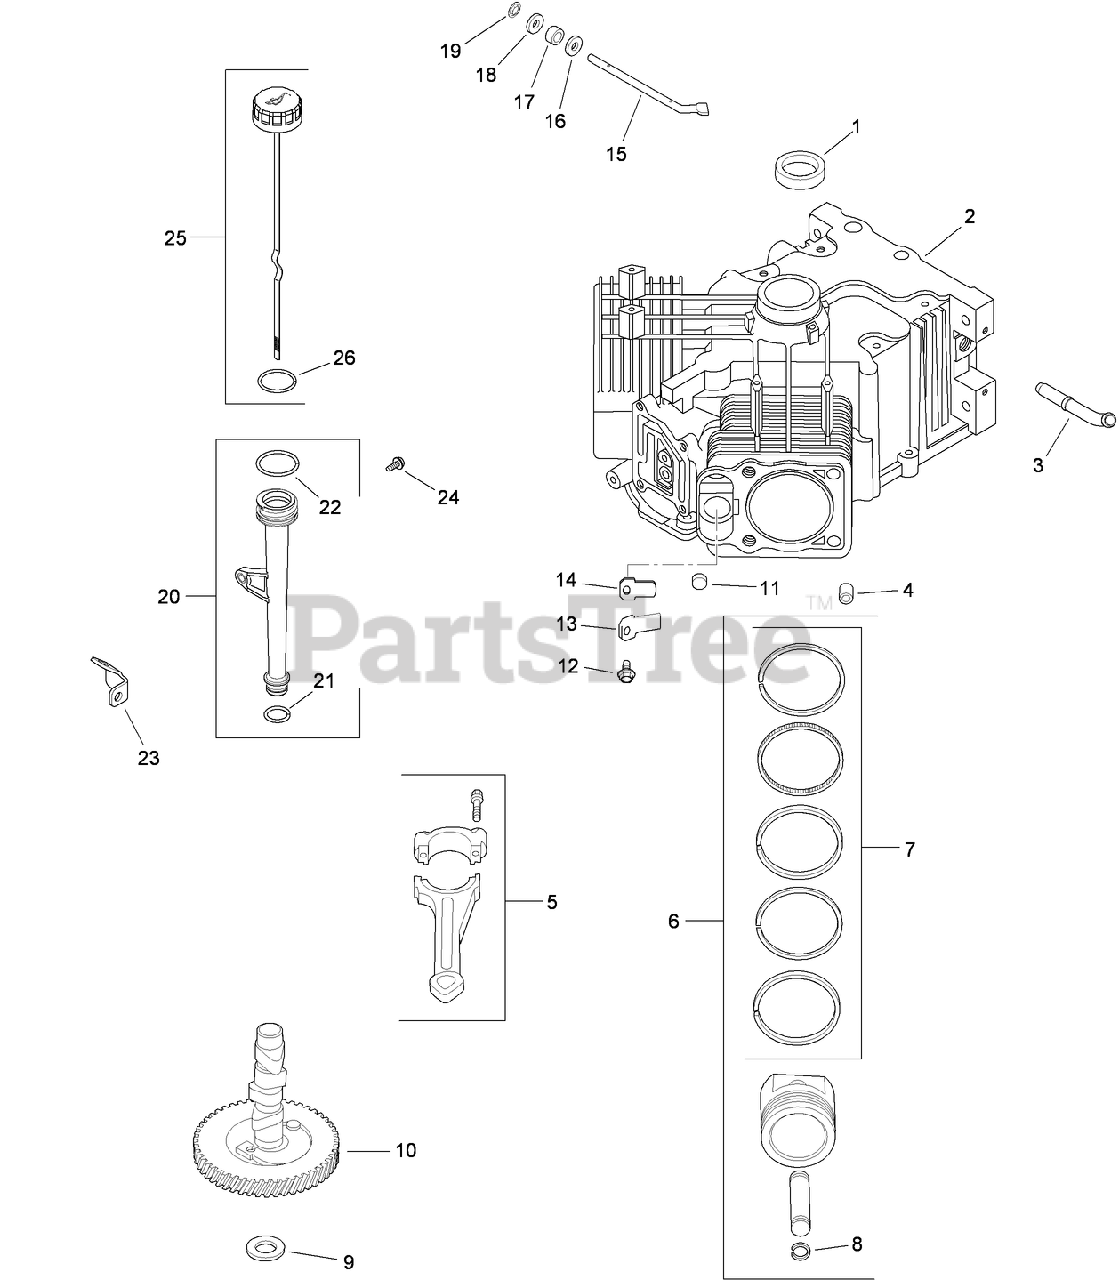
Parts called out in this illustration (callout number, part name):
1	SEAL-OIL
2	SHORT BLOCK (CV730)
2	MINI BLOCK (CV25)
3	Fitting
4	PIN-LOCATING
5	ROD-CONNECTING (STD)
5	ROD-CONNECTING (.25)
6	Piston and Ring Set (STD) (INCLUDES 7, 8)
6	Piston and Ring Set (.08)
6	Piston and Ring Set (.25)
6	Piston and Ring Set (.50)
7	Ring Set (.25)
7	Ring Set (.50)
8	RETAINER-PIN, PISTON
9	SHIM-CAMSHAFT (WHITE .028)
9	SHIM-CAMSHAFT (BLUE .03)
9	SHIM-CAMSHAFT (RED .032)
9	SHIM-CAMSHAFT (YELLOW .034)
9	SHIM-CAMSHAFT (GREEN .036)
9	SHIM-CAMSHAFT (GRAY .038)
9	SHIM-CAMSHAFT (BLACK .04)
10	Camshaft
11	PLUG-CUP
12	SCREW-HHFTF (M5X.80X10)
13	RETAINER-REED, BREATHER
14	Reed-Breather
15	SHAFT-CROSS, GOVERNOR
16	WASHER-FLAT (11/32)
17	SEAL-CROSS SHAFT, GOVERNOR
18	WASHER-FLAT (9MM)
19	RETAINER-RING
20	OIL FILL TUBE KIT (INCLUDES 21, 22)
21	O-RING (LOWER OIL FILL TUBE)
22	O-RING (UPPER OIL FILL TUBE)
23	BRACKET-TUBE, OIL FILL
24	SCREW-FLANGE, THREAD FORMING (M5X0.8X16)
25	Dipstick ASM (INCLUDES 26)
26	O-RING (DIPSTICK)
